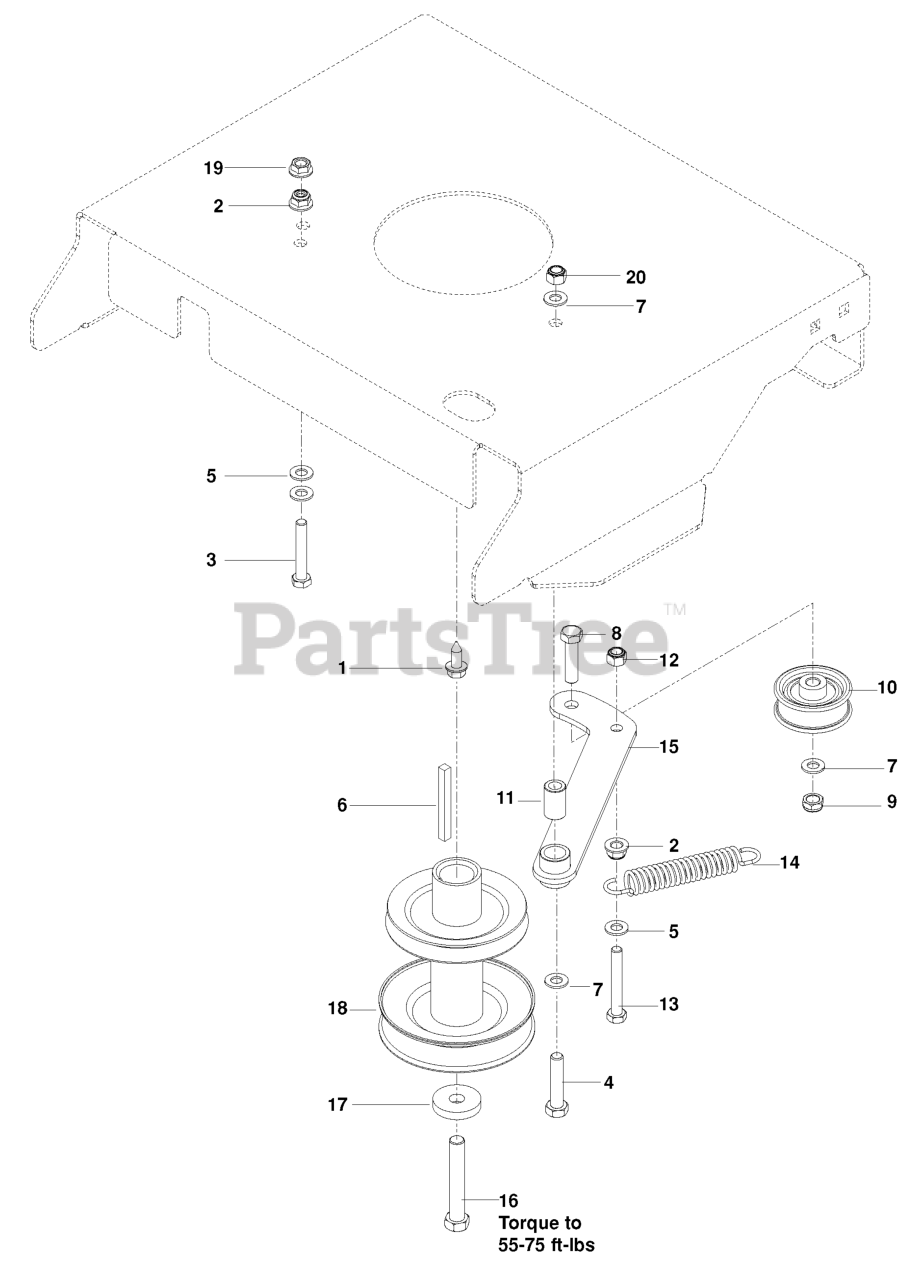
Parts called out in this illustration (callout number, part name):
1	HHFS 3/8-16 X 1.0 THD FORMING
2	5/16-18 NYLOC FLANGE NUT
3	HCS 5/16-18X2
4	HCS 3/8C X 2
5	FLAT WASHER 5/16 SAE
6	KEY 1/4 SQ X 2-1/2
7	WASHER 3/8 FLAT
8	HCS 3/8C X 1 1/2
9	NUT HEX 3/8-16 NYLON, THIN
10	PULLEY IDLER
12	NUT 5/16 NYLOC
14	SPRING - 3.50
15	IDLER WLDT.
16	HCS 7/16-20 X 2-3/4
17	WASHER .43X1.38X.25
18	PULLEY, ENGINE 30"
19	NUT 5/16C WHIZ
20	NUT 3/8-16 NYLOC
